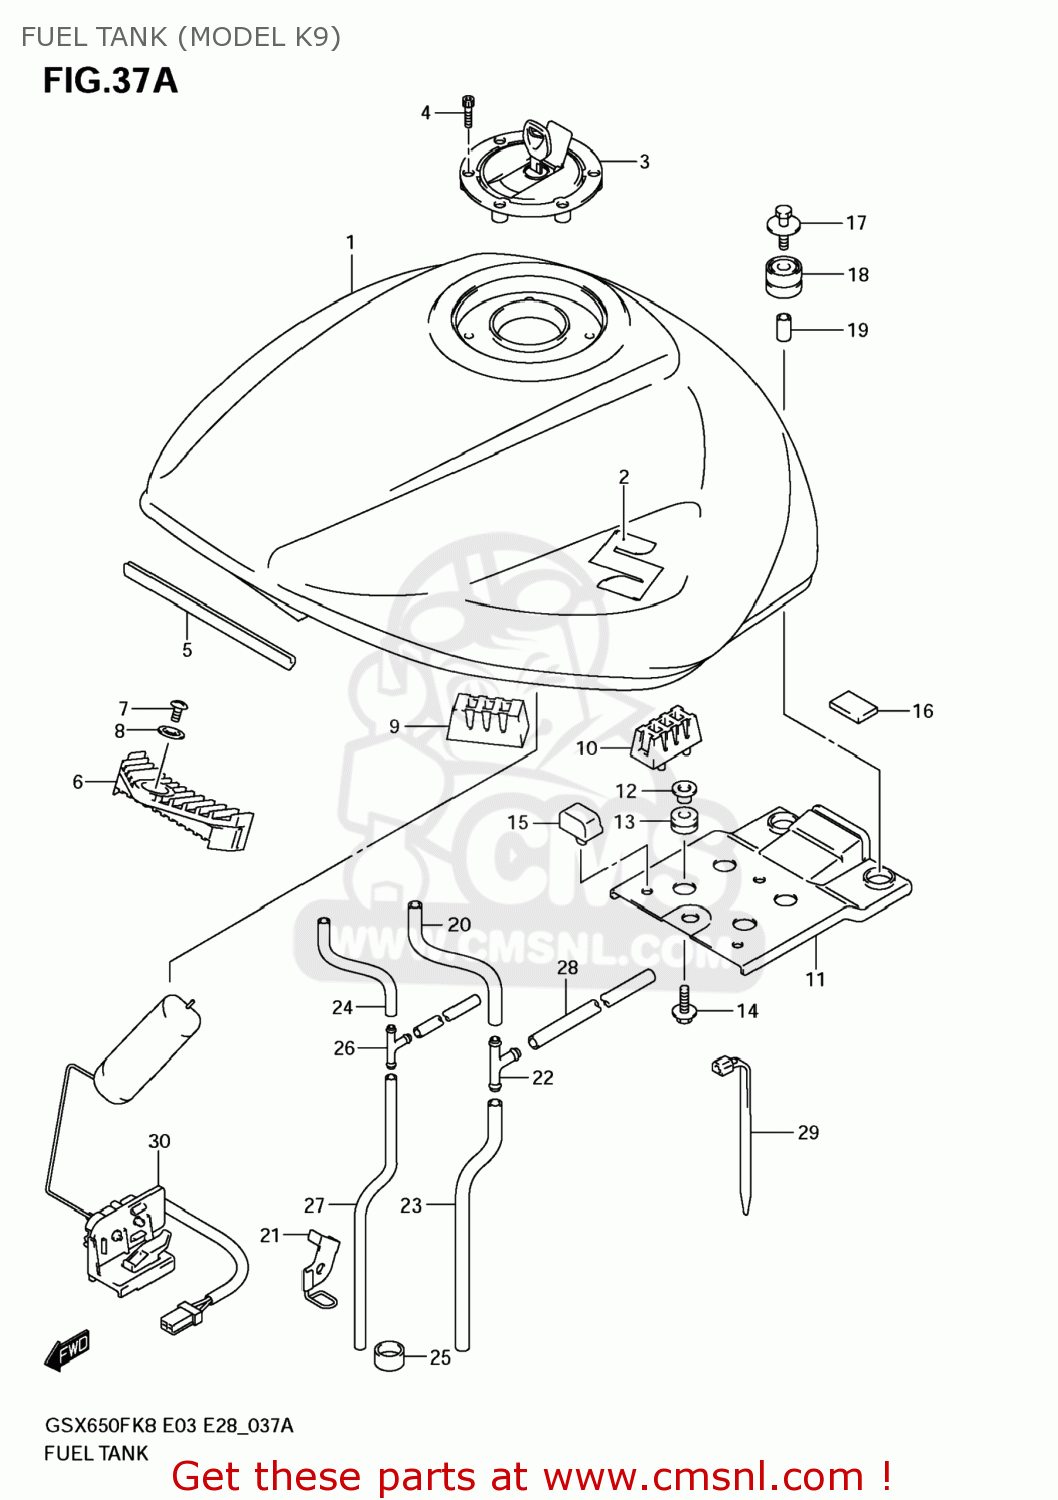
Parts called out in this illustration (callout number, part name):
1	TANK ASSY,FUEL(ORANGE)
2	EMBLEM,S
3	CAP SET,FUEL TANK
4	BOLT(5X20)
5	MOLDING
6	CUSHION,FUEL TANK FR
7	SCREW
8	WASHER
9	CUSHION,SUPPORT(50X25X32)
10	CUSHION,TANK SIDE
11	BRACKET,FUEL TANK RR
12	WASHER
13	CUSHION
14	BOLT(6X20)
15	CUSHION
16	CUSHION,SIDE COVER BRACKET
17	BOLT(6X30)
18	CUSHION,FUEL TANK RR BRKT
19	SPACER(6.5X9X18)
20	HOSE,WATER DRAIN
21	GUIDE,DRAIN HOSE
22	3-WAY [FILTER TO PUMP)
23	HOSE(7X10.2X600)
24	HOSE,TANK BREA
25	HOSE(13.5X16.5X10)
26	JOINT,3 WAY
27	HOSE(5X8.2X600)
28	HOSE(5X8.2X2000)
29	CLAMP(L:125)
30	GAUGE ASSY,FUEL LEVEL SENDER
